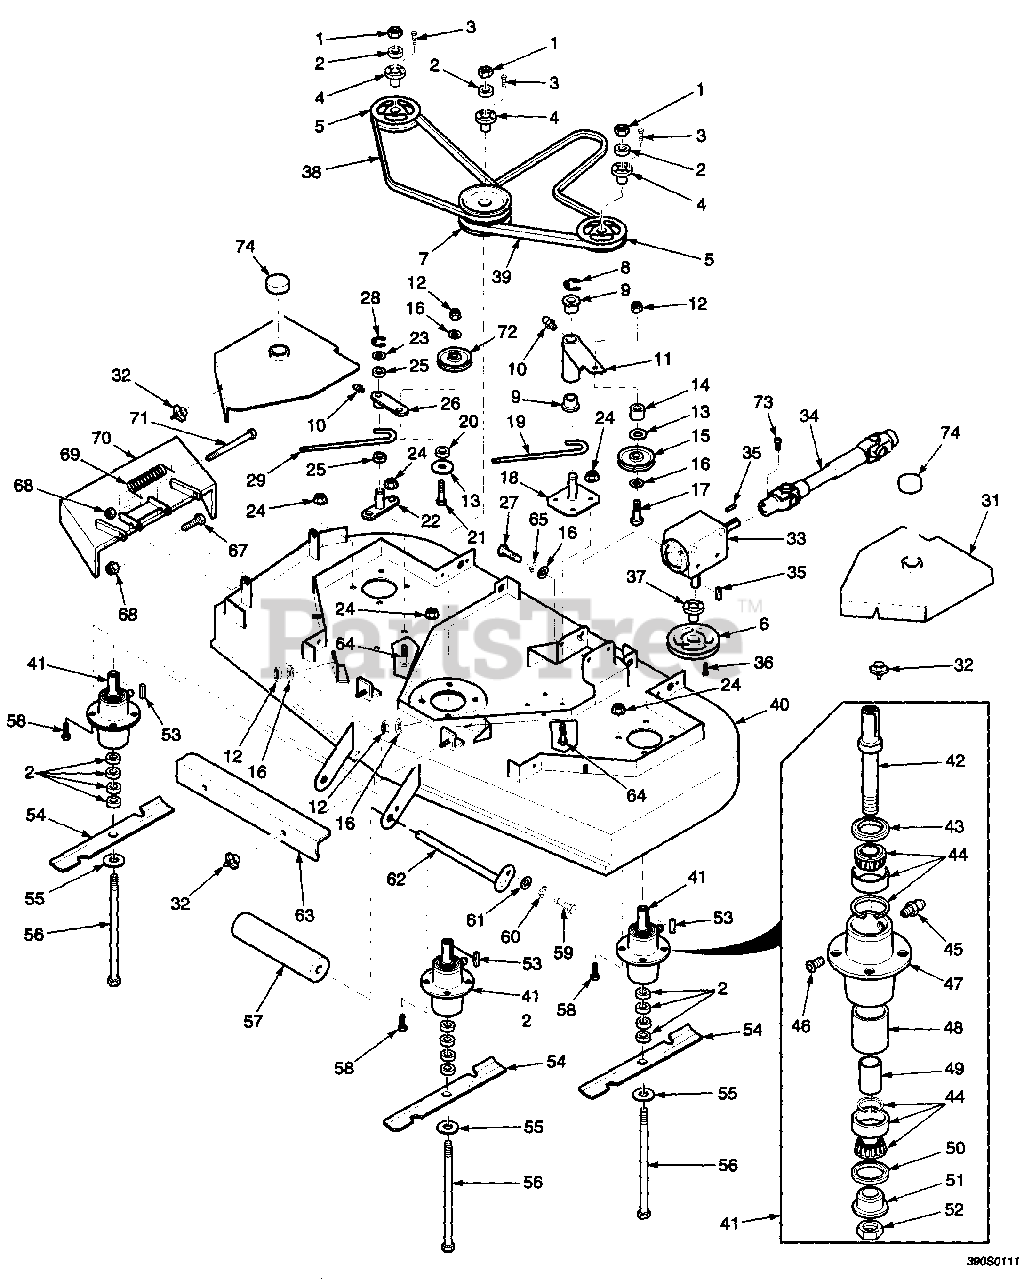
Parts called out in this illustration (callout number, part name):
1	Nut, Hex, 5/8-11
2	Spacer, Cutter Blade
3	Bolt, Hex Head, 1/4-20 x 3/4 Gr.5
4	Taper Hub, 1.125 Bore
5	Pulley, 5.75 Dia.
6	Pulley, 5.75 Dia.
7	Pulley, 5.75 Double Groove
8	Retaining Ring, .75 Ext "E"
9	Bushing, Oilite - 1.125 ID
10	Grease Fitting
11	Arm, Idler
12	Locknut, Elastic Stop, 3/8-16
13	Flat Washer, 3/8 (.375 x 1.50 x .060)
14	Spacer, J-Hook
15	Pulley, Idler
16	Flatwasher, 3/8 (.391 x .938 x .105)
17	Bolt, Hex Head, 3/8-16 x 3
18	Pivot, Idler Arm
19	J-Hook
20	Spacer, J-Hook
21	Bolt, Hex Head, 3/8-16 x 2-1/4
22	Idler Pivot
23	Flatwasher, 3/4 (.776 x 1.25 x .059)
24	Serr. Fl. Hex Nut, 5/16-18
25	Bushing, Oilite - 3/4 ID
26	Idler Arm
27	Bolt, Hex Head, 3/8-16 x 1
28	Retaining Ring, .75 Ext "E"
29	Pull Rod, Idler
31	Belt Cover, LH
32	Wingnut, Plastic, 3/8-16
33	Gearbox, Deck Drive
34	Drive Shaft
35	Key, 1/4 x 1/4 x 1-1/4
36	Bolt, Hex Head, 1/4-20 x 1-3/8
37	Tapered Hub, 1.00 Bore
38	Belt, Cutter Deck
39	Belt, Cutter Deck
40	Cutter Deck with Decals
41	Spindle Assembly
42	Shaft, Cutter Spindle
43	Seal, 2.00 OD x 1.50 Bore
44	Bearing Assembly
45	Grease Fitting
46	Relief Fitting, Cutter Spindle
47	Spindle Housing
48	Spacer, Outside
49	Spacer, Inside
50	Seal, 2.00 OD x 1.625 OD
51	Spindle Bushing, Bottom
52	Nut, 1-1/16-18 UNEF-2B
53	Key, 1/4 x 1/4 x 2
54	Blade, 24-1/2"
55	Washer, 5/8 (.688 x 1.75 x .134)
56	Bolt, Hex Head, 5/8-11 x 9-1/2 Gr.5
57	Roller
58	Bolt, Hex Head, 5/16-18 x 1-1/4
59	Bolt, Hex Head, 5/16-18 x 3/4
60	Lockwasher, 5/16
61	Flatwasher, 5/16 (.375 x .875 x .083)
62	Shaft, Roller
63	Cover, Belt - Front
64	Serr. Fl Hex Head Capscrew, 5/16-18 x 3/4
65	Lockwasher, 3/8
67	Bolt, Hex Head, 5/16-18 x 1.0
68	Hex Locknut, Elastic Stop, 5/16-18
69	Spring, Discharge Chute
70	Discharge Chute
71	Bolt, Hex Head, 5/16-18 x 4-1/4
72	Pulley, Idler
73	Set Screw, Hex Socket, 3/8-16 x 1/2
74	Spindle Shield
